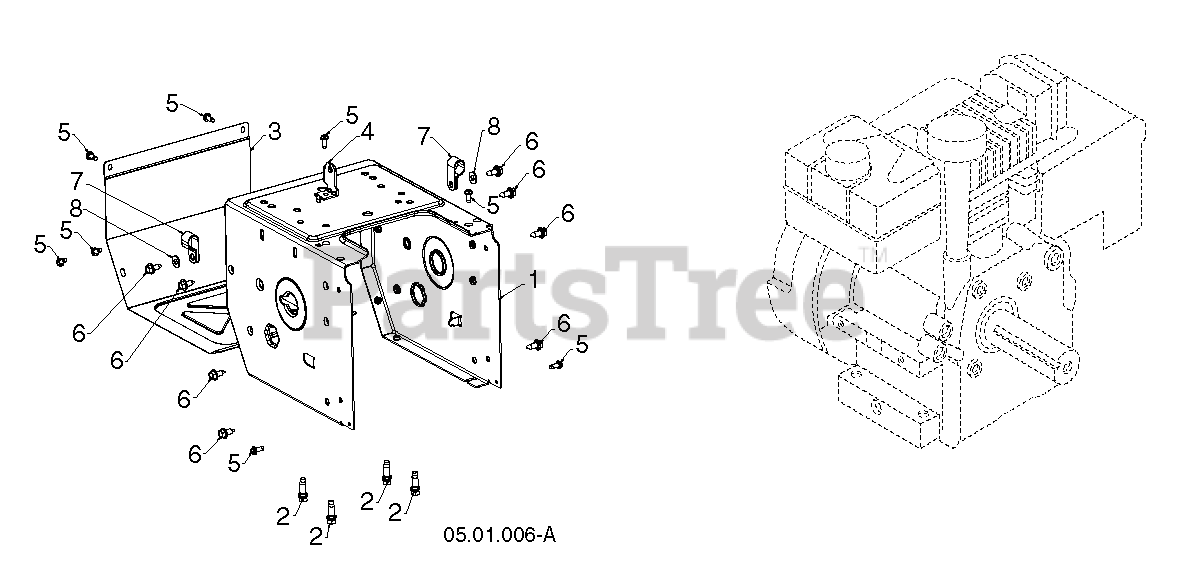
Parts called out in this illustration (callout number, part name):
1	FRAME.GEAR.CASE.SNOW.BLACK
2	BOLT 3/8-16X1-1/8
3	Snow Frame Cover, Black
4	BRACKET.SHIFTER.BZP
5	SCREW 14-20 X 5/8
6	BOLT.HEX.HD.WASHER.5/16-18X.75
7	CLIP.CABLE.BLK
8	WASHER.FLAT.343X.750X16 GA BLK
